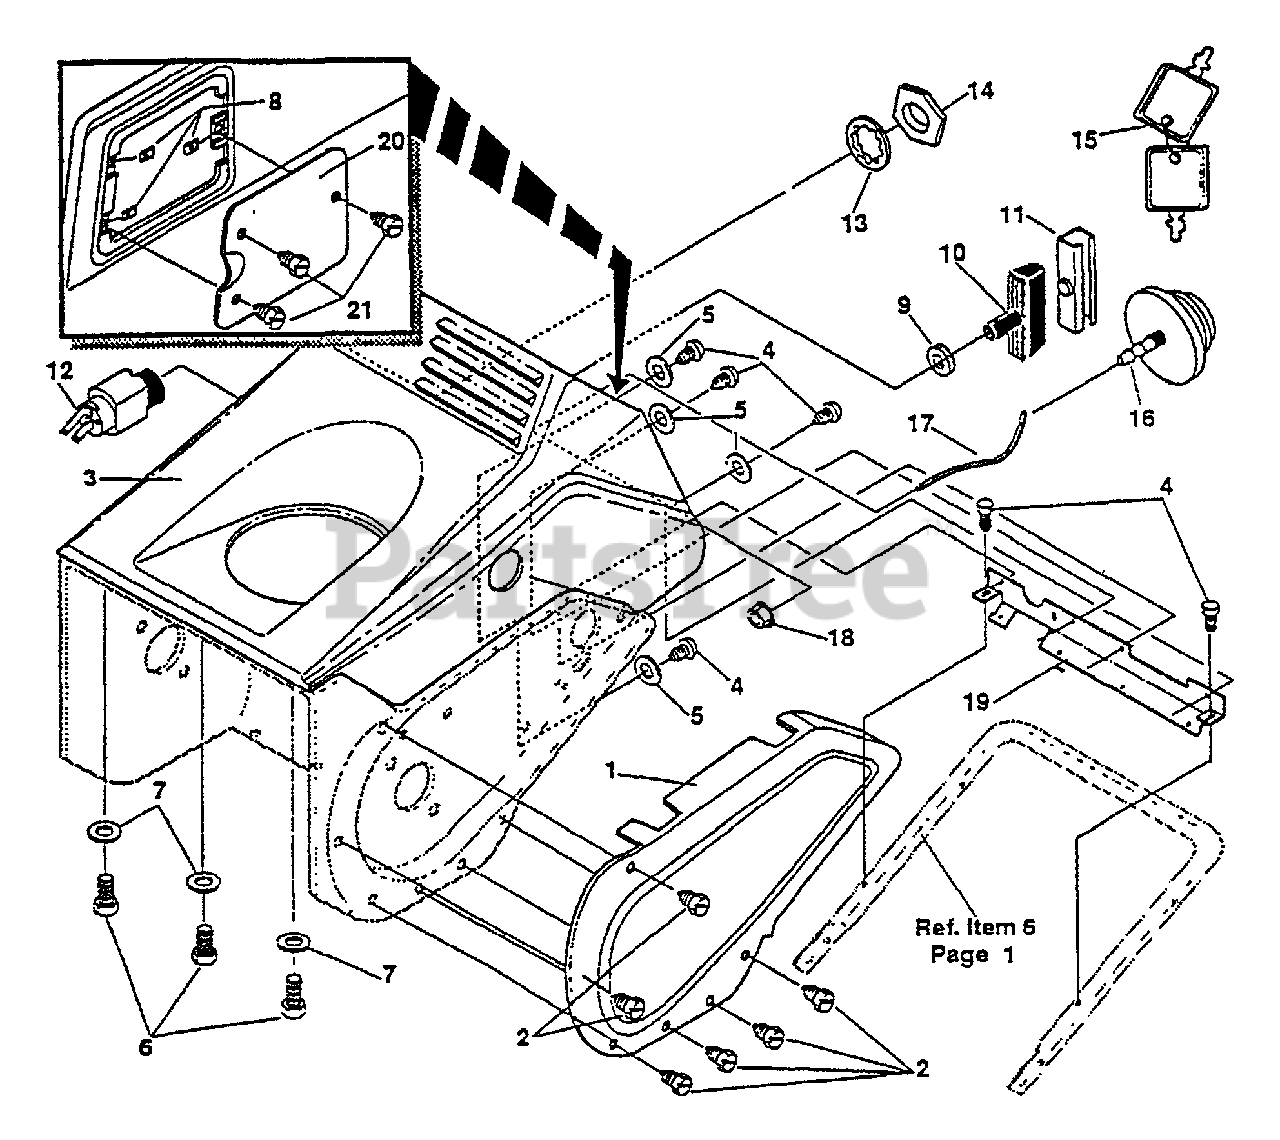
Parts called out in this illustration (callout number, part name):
1	COVER, BELT
2	SCREW
3	COVER
4	SCREW - 10-24×0.63" -- PAN HEAD
5	WASHER
6	SCREW
7	WASHER
8	NUT
9	GUIDE, ROPE
10	KNOB, SHORT SHANK
11	INSERT METAL, KNOB
12	SWITCH, IGNITION
13	WASHER
14	NUT
15	KEYS & RING ASSY
16	PRIMER, ENGINE 2CY
18	NUT
19	BRACKET
20	DOOR, ACCESS
